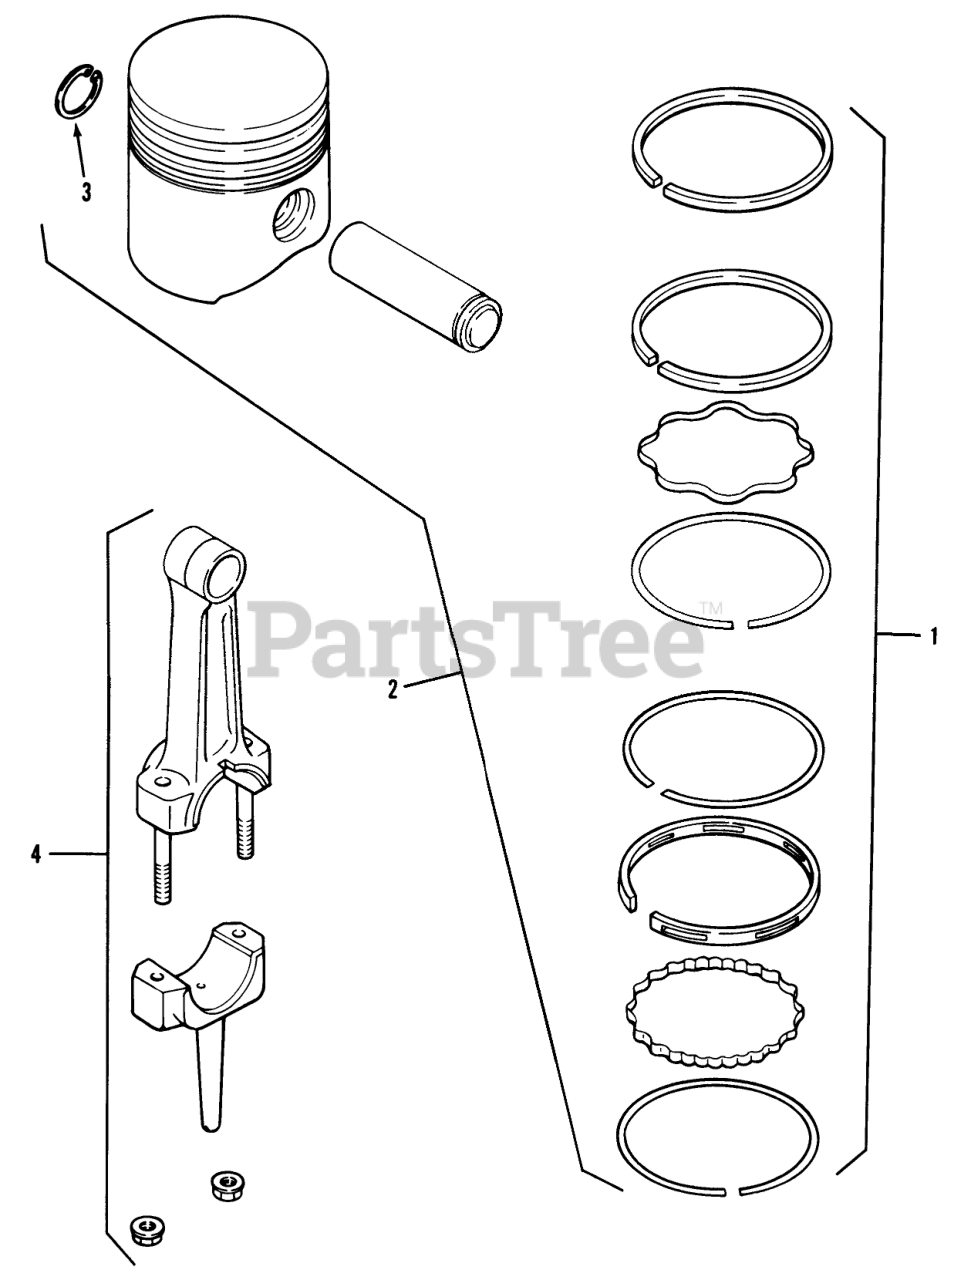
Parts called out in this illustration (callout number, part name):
1	Set-Ring, Std. & .003
2	Piston w/Ring Set Std
3	Piston Pin Retainer
4	Rod-Connecting Std.
